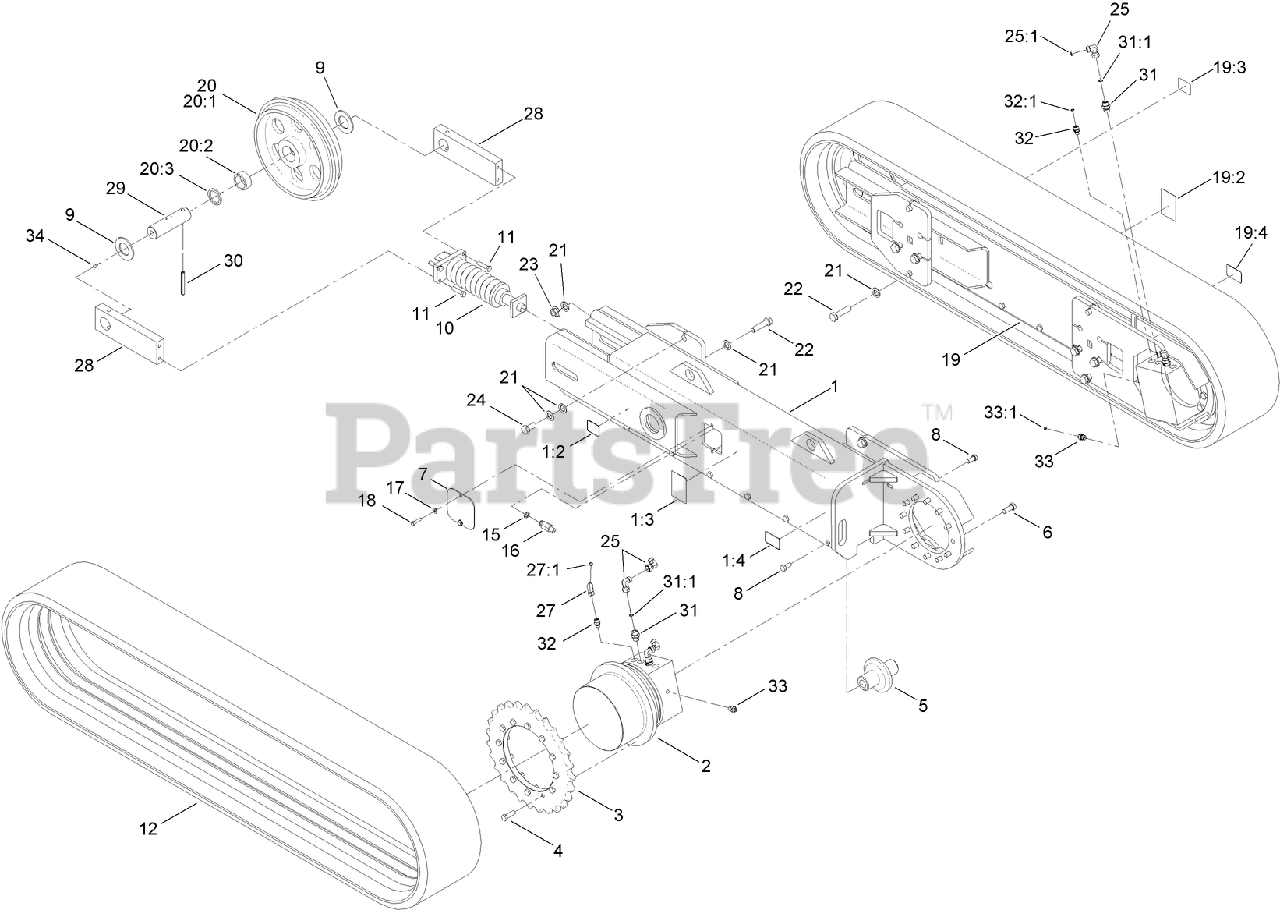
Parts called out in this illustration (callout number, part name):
1	RH TRACK POD ASM
1:2	DECAL-TIE DOWN
1:3	DECAL-WARNING, THROWN OBJECTS
1:4	DECAL-LIFT/TIE DOWN
2	PLANETARY GEARBOX ASM
3	SPROCKET-TRACK DRIVE, 27T
4	SCREW-HH
5	ROLLER-TRACK
6	SCREW-HH
7	COVER-ACCESS HOLE
8	SCREW-HH
9	BEARING-THRUST
10	TENSIONER-TRACK
12	TRACK-RUBBER
15	SEAL-O RING
16	VALVE-GREASE
17	WASHER-FLAT
18	SCREW-HH
19	LH TRACK POD ASM
19:2	DECAL-WARNING, THROWN OBJECTS
19:3	DECAL-TIE DOWN
19:4	DECAL-LIFT/TIE DOWN
20	IDLER ASM
20:1	SPROCKET-IDLER
20:2	BEARING
20:3	SEAL-SHAFT
21	WASHER
22	SCREW-HH
23	NUT-HHF
25	FITTING-HYD
25:1	O-RING
27	FITTING-HYD, 90 DEG
27:1	O-RING
28	SLIDER-TENSIONER, TRACK DRIVE
29	PIN-AXLE
30	PIN-SLOTTED, SPRING
31	FITTING-STRAIGHT
31:1	O-RING
32	FITTING-STRAIGHT
32:1	O-RING
33	FITTING-STRAIGHT
33:1	O-RING
34	FITTING-GREASE
